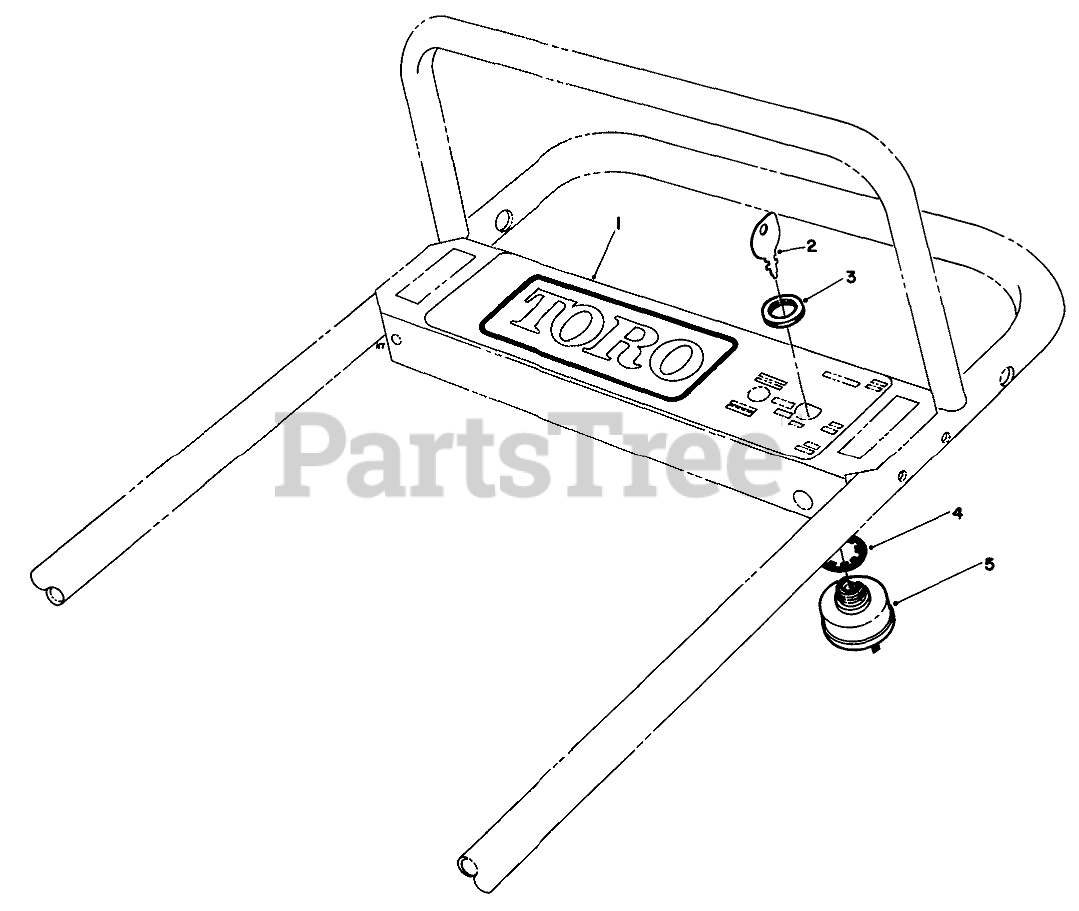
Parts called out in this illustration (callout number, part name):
1	Decal-Electric Start Panel
2	Key
3	NUT-HH
4	WASHER-TOOTH, INTERNAL
5	Ignition Switch (Incl. Ref. #2-4)
